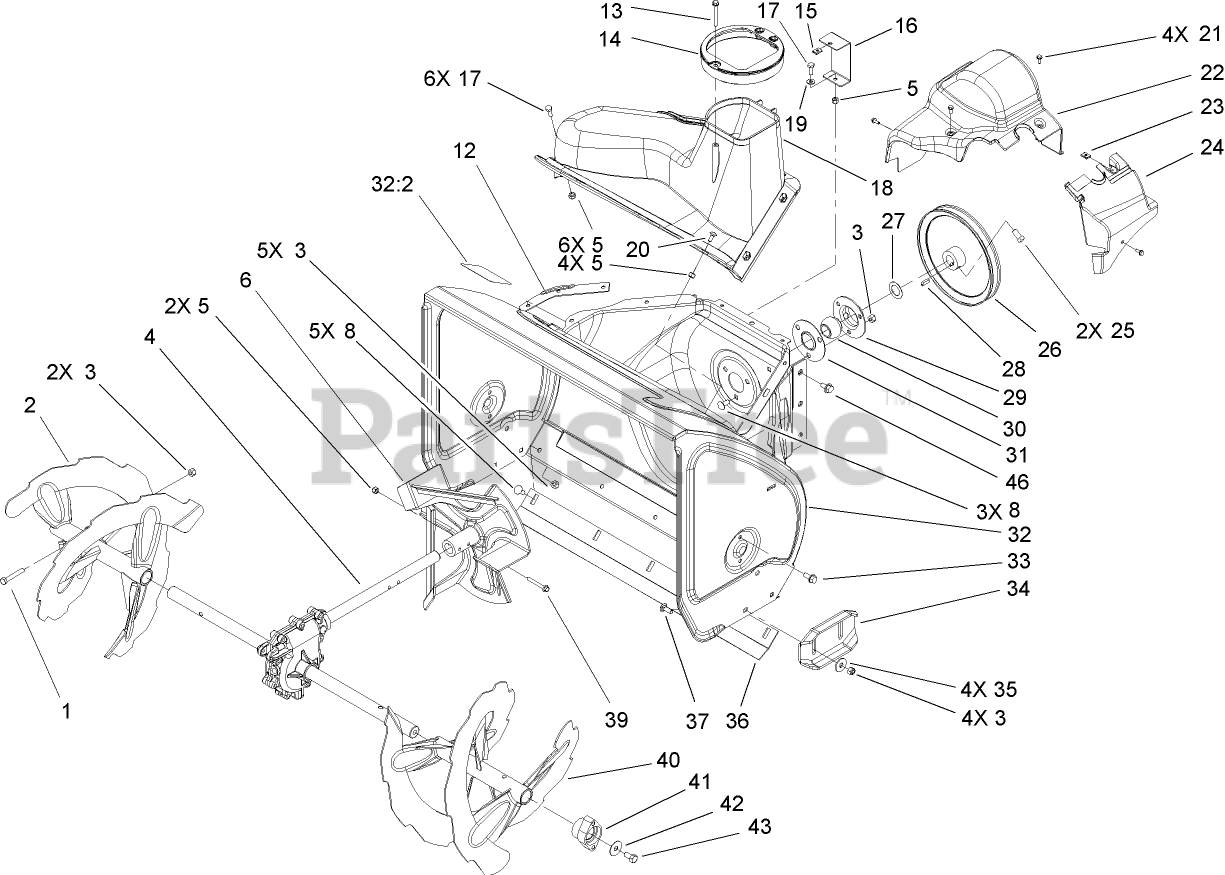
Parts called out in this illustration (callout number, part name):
1	SCREW-HH
2	RH AUGER ASM
3	NUT-LOCK, NI
5	NUT-LOCK, NI
6	IMPELLER ASM
8	SCREW-CARR
12	SEAL-FLANGE, COVER
13	SCREW-PLASTITE
14	GUIDE-CHUTE
15	NUT-SPEED
16	BRACKET-COVER, CLIP NUT
17	SCREW-HH
19	WASHER-FLAT
20	BOLT-CARR
21	SCREW-HWH
23	NUT-SPEED
24	COVER-EXTENSION, BELT
25	SCREW-SET, SQH
27	WASHER-THRUST
28	KEY-WOODRUFF
29	FLANGE-CUP, BEARING
30	BEARING-BALL
31	FLANGE-CUP, BEARING
32	HOUSING-AUGER, 26 INCH
32:2	DECAL-DANGER
33	SCREW-HWHTF
35	WASHER
36	SCRAPER-FIXED
37	SCREW-CARR
39	SCREW-HHF
40	LH AUGER ASM
41	BEARING-AUGER
42	WASHER
43	SCREW-HH
46	SCREW-HWHTF
